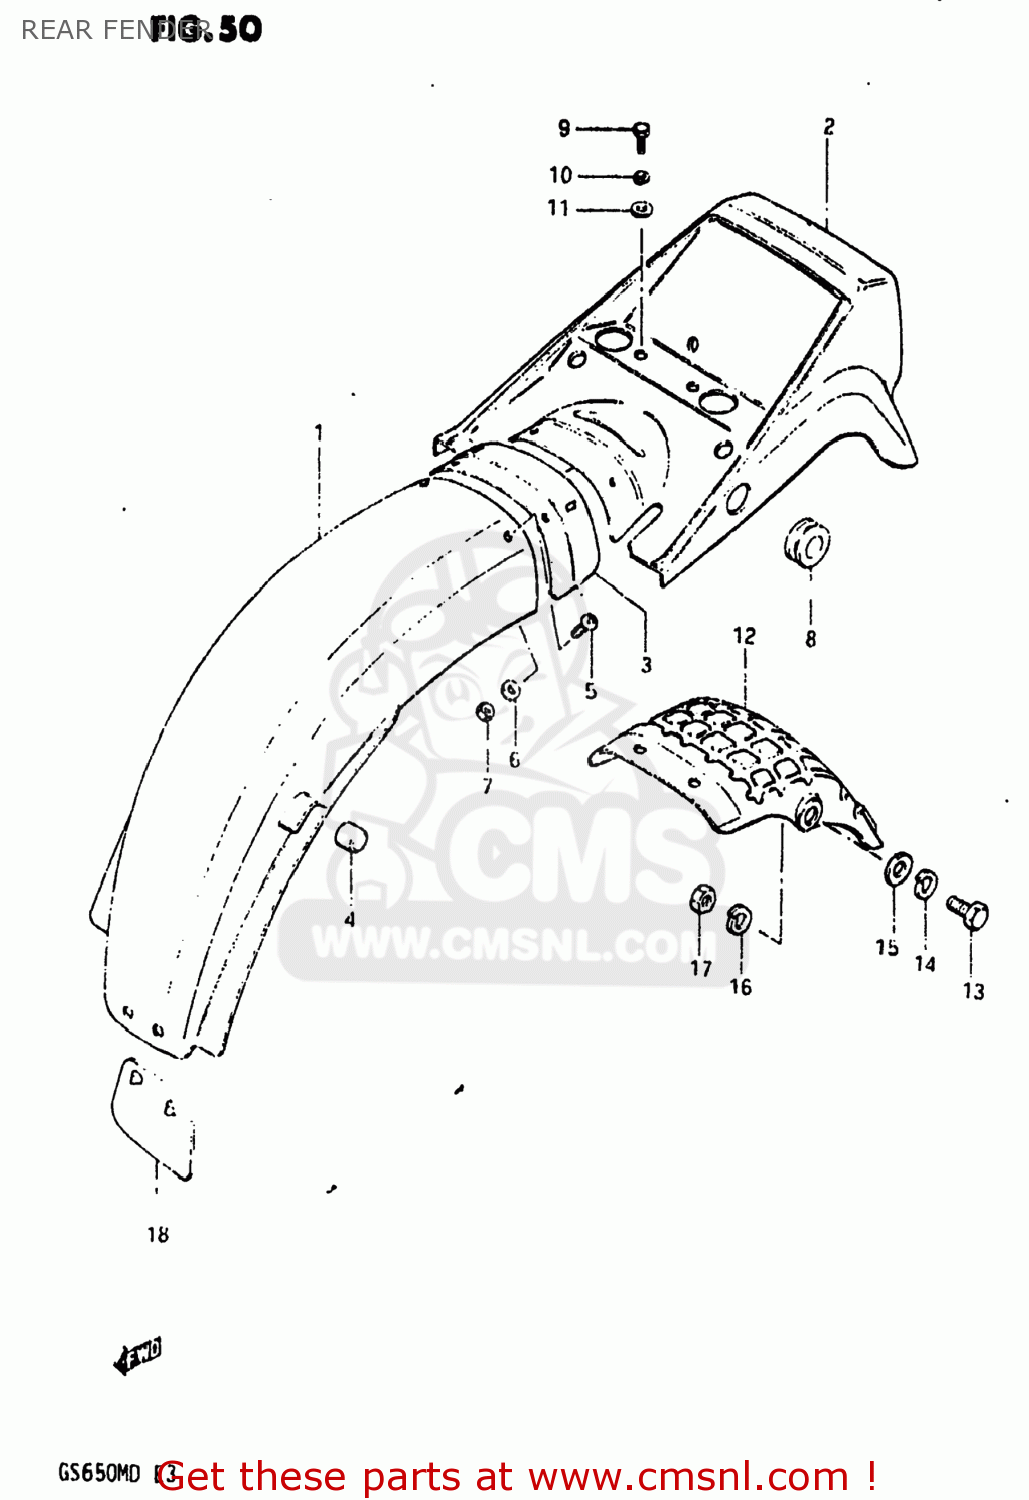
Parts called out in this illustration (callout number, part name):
1	BODY,REAR FENDER,REAR
2	FENDER,REAR
3	JOINT,REAR FENDER
4	CUSHION
5	SCREW
6	WASHER (5.5X16X1.2)
7	NUT
8	GROMMET,SEAT LOCK HOLE
9	BOLT
10	LOCK WASHER
11	WASHER
12	REINFORCEMENT,REAR FENDER
13	BOLT
14	LOCK WASHER
15	WASHER
16	LOCK WASHER
17	NUT
18	GUIDE,RR FENDER MUD
